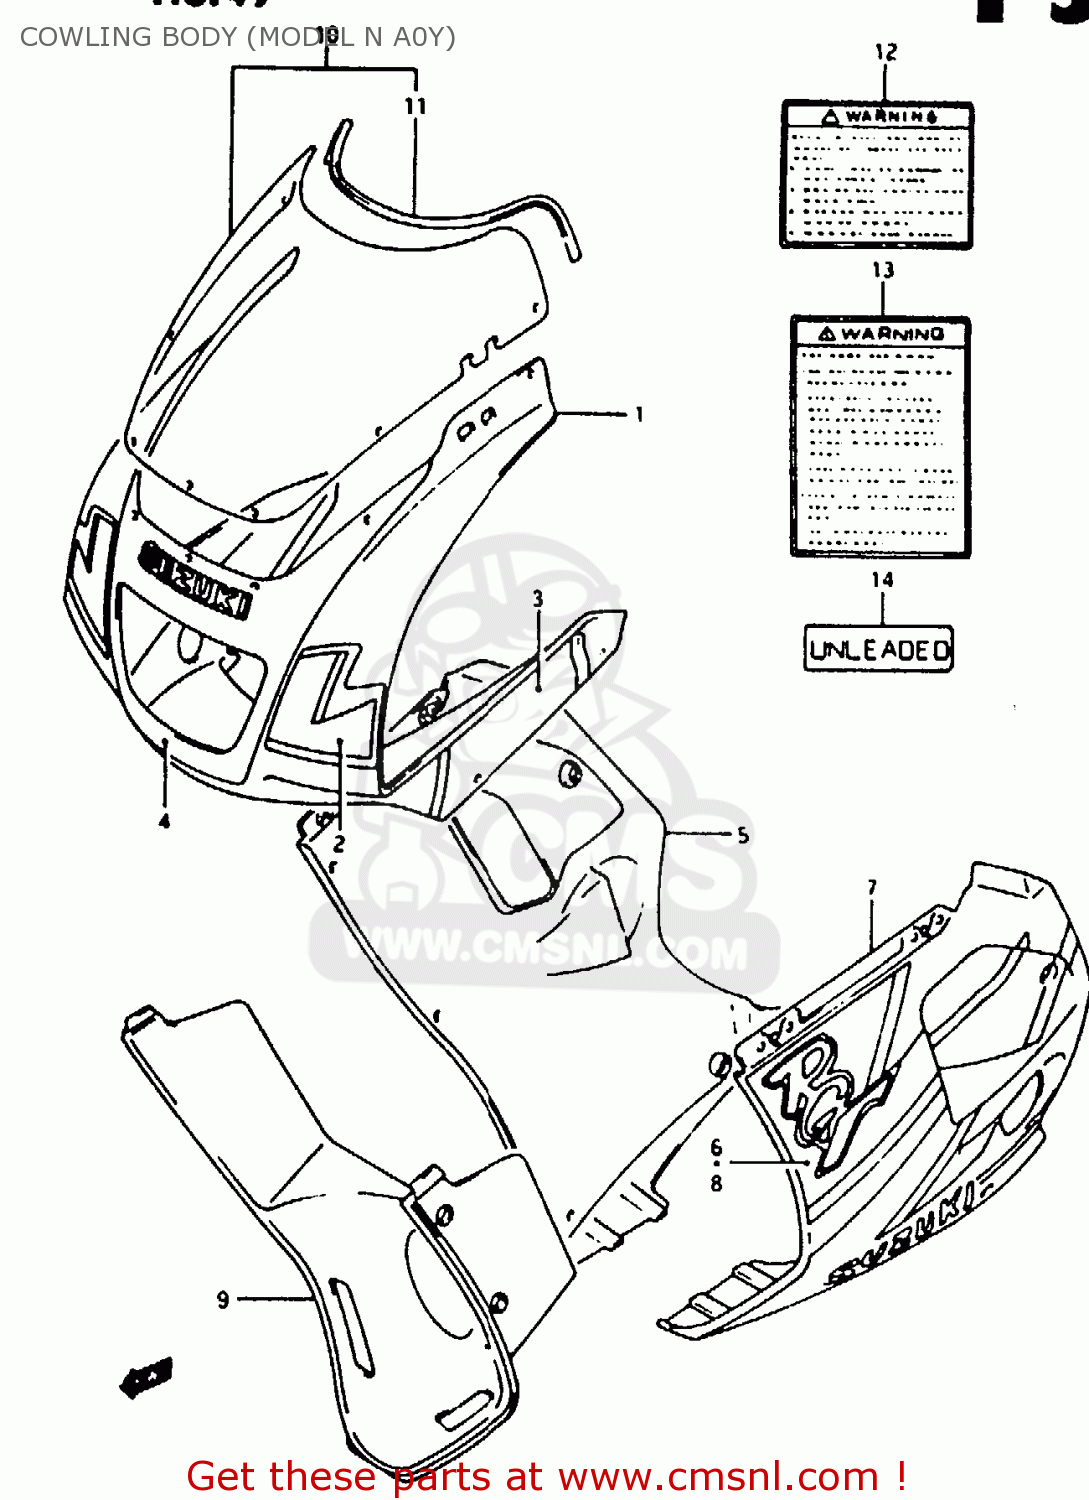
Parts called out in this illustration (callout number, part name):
1	COWLING ASSY, BODY (WHITE)
2	TAPE SET, FRONT
3	TAPE SET, SIDE
4	TAPE, ZEKKEN
5	COWLING ASSY, UNDER RH (WHITE)
6	TAPE SET, UNDER RH
7	COWLING ASSY, UNDER LH (WHITE)
8	TAPE SET, UNDER LH
9	COWLING, UNDER CENTER (WHITE)
10	SCREEN SET, WIND
11	MOLDING
12	LABEL, WARNING SAFETY
13	LABEL (WARNING SCREEN)
14	LABEL,CAUTION
15	LABEL, TIRE AIR PRESSURE
16	MANUAL, OWNER'S
